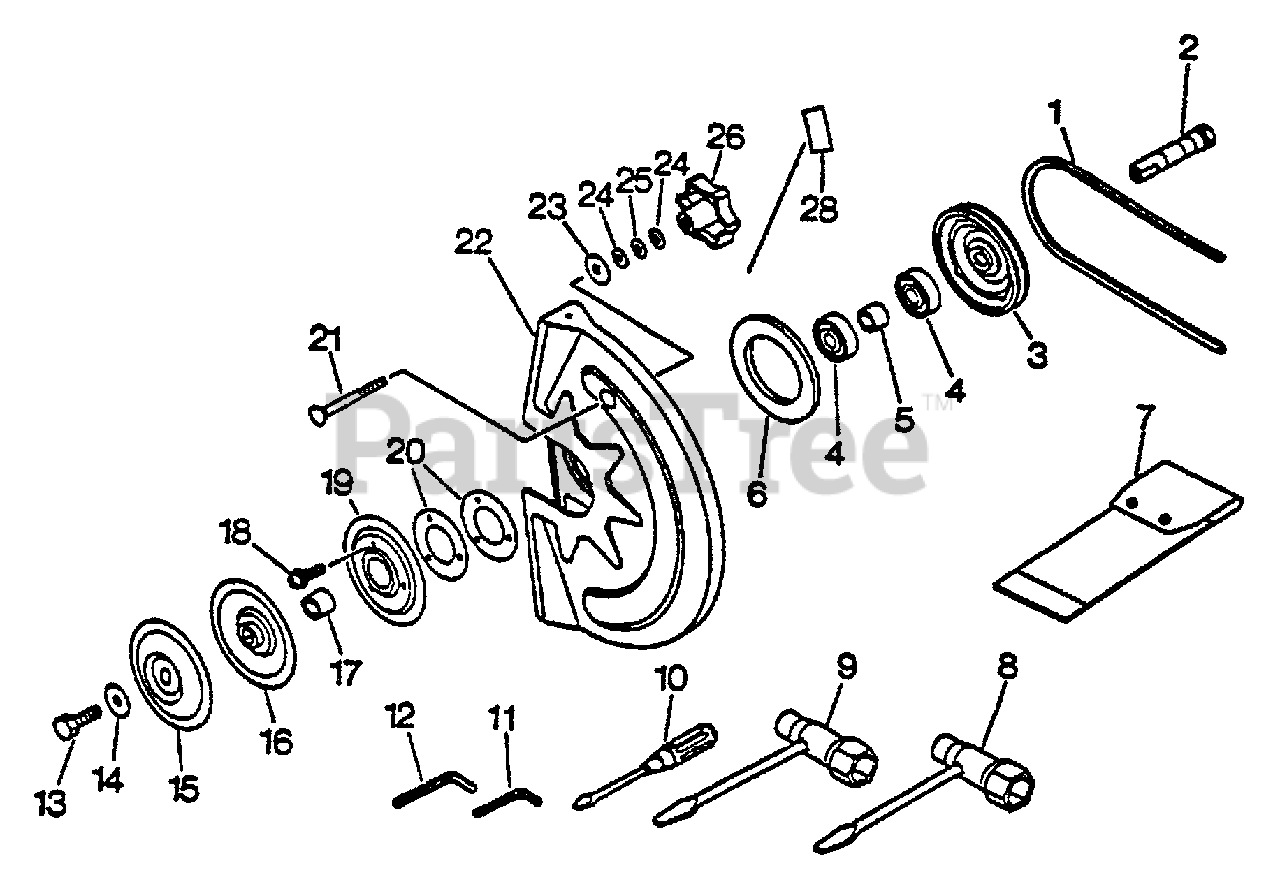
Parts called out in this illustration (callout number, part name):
4	BEARING, BALL - 6203
5	SPACER
7	BAG, TOOL
8	T-WRENCH - 13X19mm
9	T-WRENCH - 17X19mm
10	SCREWDRIVER
11	HEX KEY - 4mm
12	HEX KEY - 5mm
15	FLANGE, CUTTER
16	FLANGE, CUTTER
18	SCREW - 4X14
19	PLATE, CUTTER COVER
21	BOLT - 10X70
22	COVER, BLADE
24	WASHER - 10
25	LOCKWASHER - 10
28	LABEL - ECHO
